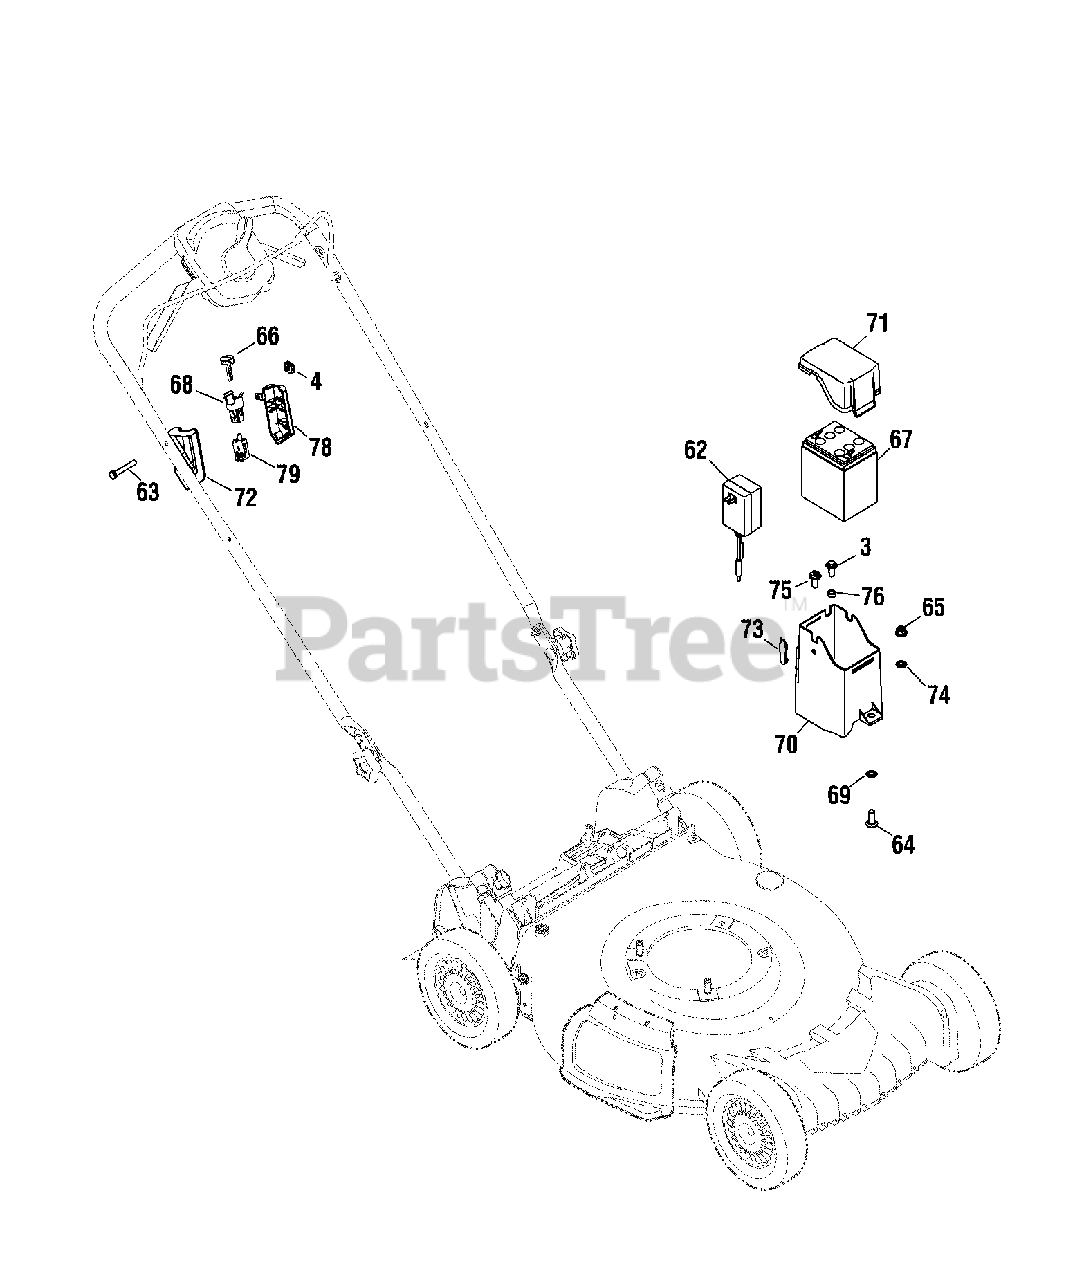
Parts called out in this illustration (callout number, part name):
3	SCREW, 5/16-14 x 3/4
4	NUT, Square, 1/4-20
62	CHARGER, Battery
63	SCREW, 1/4-20 x 1.75
64	BOLT, Carriage, 5/16-18 x 1
65	NUT, Serrated Lock Flange, 5/16-18
67	BATTERY
69	NUT, Speed
70	HOUSING, Battery
71	HOUSING, Top, Battery
72	HOUSING, Electric Start, RH
73	SEAL, Lid
74	WASHER, Bell, .340 x .872 x .080
75	BOLT, Shoulder, 5/16-14 x .972
76	SPACER, .340 x .460 x .246
78	HOUSING, Electric Start, LH
79	SWITCH, Plunger
